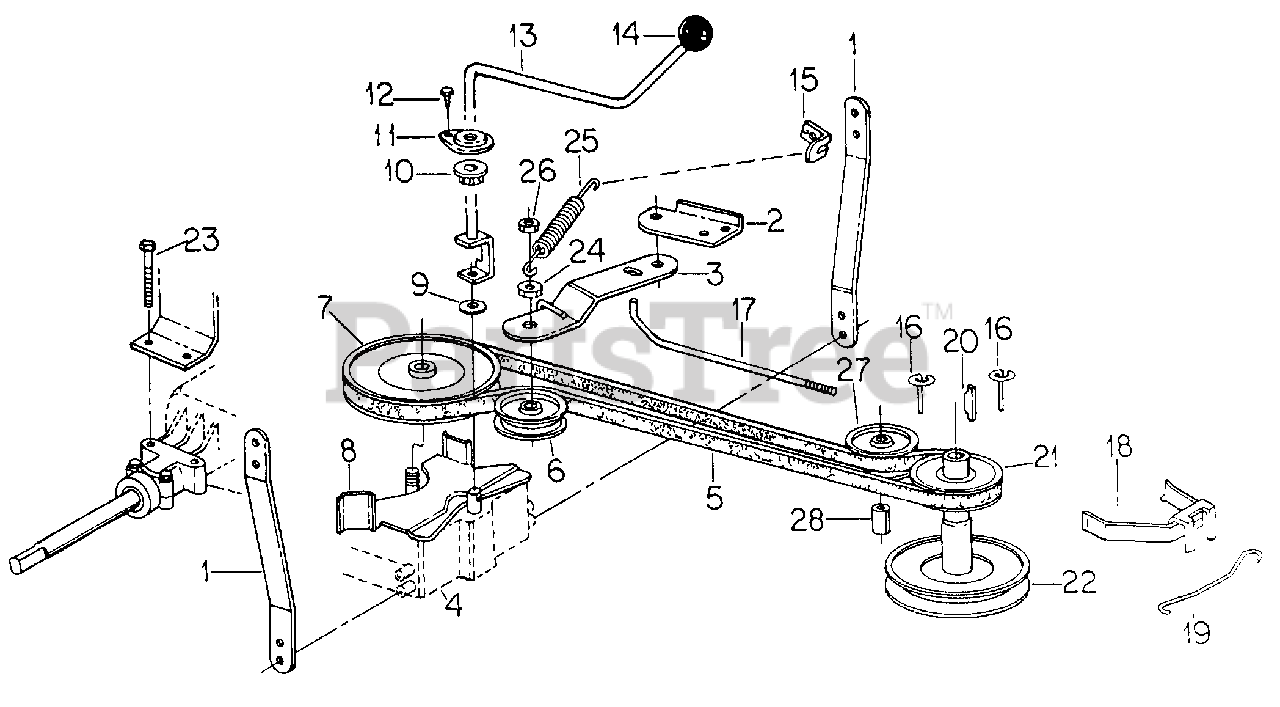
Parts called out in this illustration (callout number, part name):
1	Brace, Transmission
2	Support, Clutch Idler, Bracket
3	Bracket, Clutch Idler
4	Transaxle, 5 Speed
5	Belt, Drive
6	Pulley, Idler
7	Pulley, Transmission
8	Support, Belt Keeper
9	Washer, Shifter
10	Not used in this application
11	Bushing, Cap
12	Screw, No. 10-16 x 1/2 H/Whd Tap
13	Lever, Gear Shift
14	Knob, Shifter
15	Support, Steering Rod, Bracket
16	Rod, Belt Guide
17	Rod, Clutch
18	Guide, Engine Belt
19	Support, Belt Guide
20	Key, 1/4 x 2-3/4 Sq Parallel
21	Pulley, Engine Drive
22	Pulley, Mower Drive
23	Bolt, 5/16 x 2-1/4 Type 5
24	Nut, 3/8 Type 5
25	Spring, Idler
26	Nut, 3/8 Cad P/T Lock Type 5
27	Pulley, Idler
28	Bushing, Spacer
